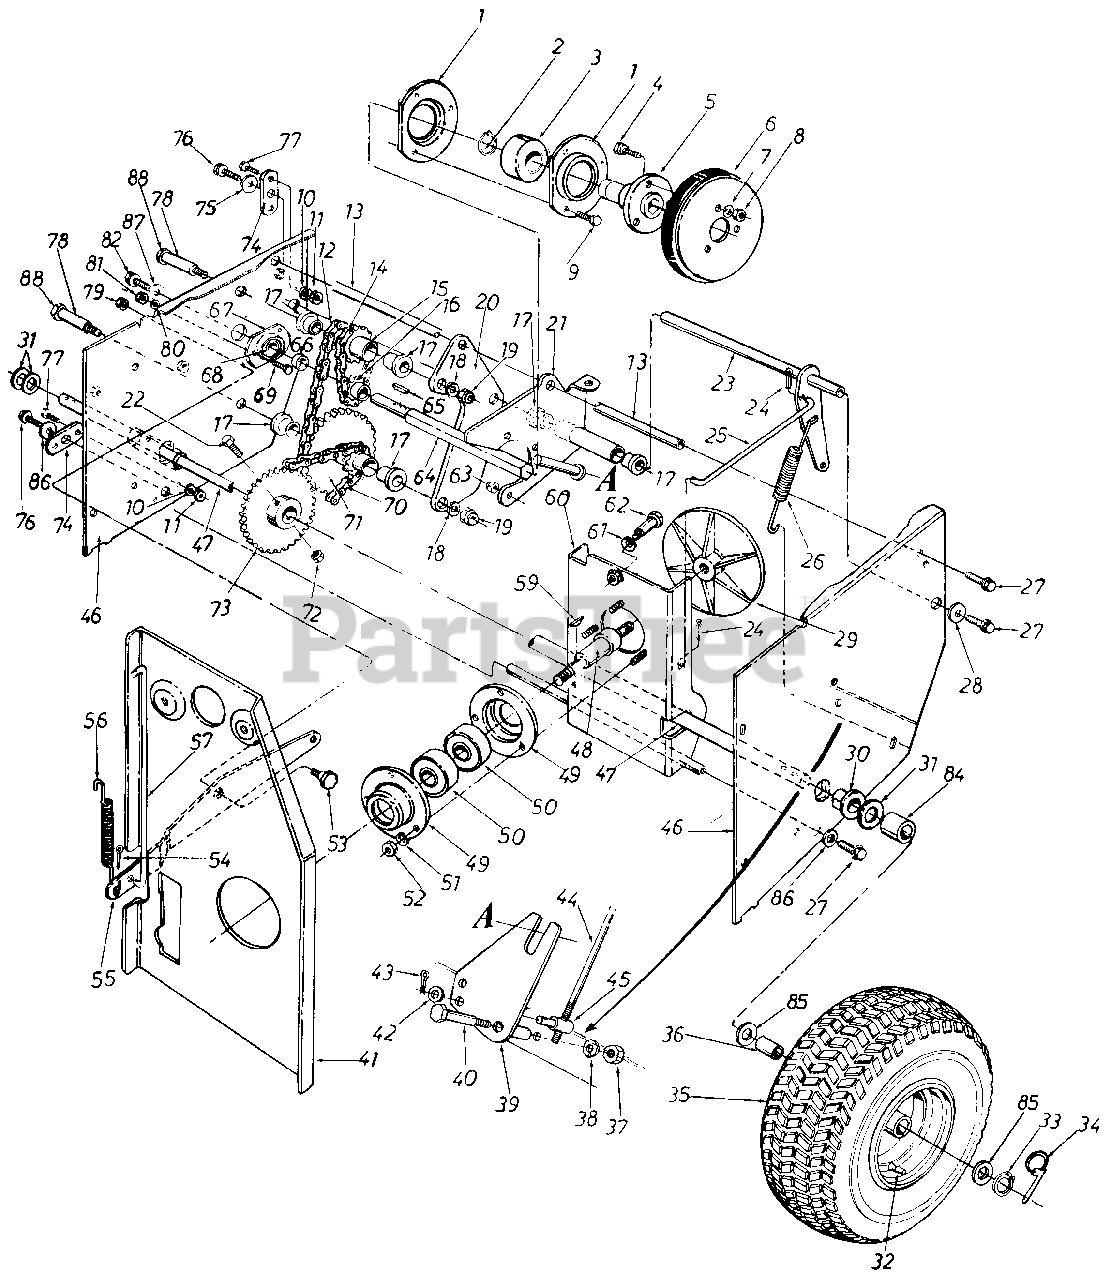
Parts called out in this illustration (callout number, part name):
1	Bearing Housing
2	Snap Ring-1.0" Dia.
3	Bail Brg. .25MM x 52MM x 15MM Thk.
4	Hex Sems Bolt 5/16-18 x .75" Lg.*
5	Friction Wheel Adapter
6	Friction Wheel Ass'y.
7	L-Wash. 5/16" I.D.*
8	Hex Nut 5/16-18 Thd.*
9	Hex Bolt 1/4-28 x .62" Lg.
10	L-Wash. 1/4" I.D.*
11	Hex Nut 1/4-20 Thd.*
12	#41 Chain-1/2" Pitch x 43 Links
12	Master Link (Service Only)
13	Sliding Support Axle
14	#41 Chain-1/2" Pitch x 19 Links
14	Master Link (Service Only)
15	9 and 14 Teeth Sprocket Hub Ass'y.
16	8 Teeth Sprocket
17	Flange Bearing .63" I.D.
18	L-Wash. 3/8" I.D.-H.D.
19	Hex L-Jam Nut 3/8-24 Thd.
22	Hex Bolt 1/4-28 x 1.5" Lg.
23	Drive Clutch Brkt. Ass'y.
24	Inter. Cot. Pin 5/16" Dia.*
25	Drive Clutch Rod .31" Dia. x 7.38" Lg.
26	Extension Spring 4.31" Lg.
27	Hex L-Bolt 5/16-18 x .62"
28	Fl-Wash. .345" I.D. x .75" O.D.
29	Aluminum Drive Plate
30	Flange Brg. w/Flats
31	Fl-Washer
32	Tubeless Air Valve
33	Snap Ring 3/4" Shaft
34	Klick Pin
35	Wheel Ass'y. Comp. 15 x 6
35	Rim Only
36	Bearing.75" I.D.
37	Hex Jam Nut 3/8-16 Thd.
38	L-Wash. 3/8" I.D.*
41	452 Engine Brkt. Ass'y.
42	Fl-Wash. .344" I.D. x .62" O.D.
43	Cotter Pin 3/32" Dia. x .75"-Lg.*
44	Shifting Rod
45	Adjustment Ferrule
46	452 Frame Ass'y.
47	Free Wheeling Axle
48	Drive Plate Spindle
49	Bearing Housing
50	Ball Brg. .787" I.D. x 1.85" O.D.
51	L-Wash. 5/16" I.D.
52	Hex Nut 5/16-18 Thd.*
53	Shld. Bolt .625" Dia. x .170" Lg.
54	Inter. Cotter Pin 5/16" Dia.*
55	Auger Clutch Brkt.
56	Extension Spring .38" O.D. x 3.18" Lg.
57	Auger Clutch Rod .31" Dia. x 10.62" Lg.
59	#61 Hi-Pro Key 3/16" x 5/8" Dia.
62	Shld. Bolt
63	Hex Ins. Jam Nut 1/4-28 Thd.
64	Hex Shaft
65	#9 Hi-Pro Key 3/32" x 5/8" Dia.
66	Spacer .51" I.D. x .69" O.D.
67	Bearing Housing
68	Ball Bearing
69	Hex Bolt 1/4-20 x .62" Lg.
70	#420 Chain .50" Pitch x 29 Links
70	Master Link
71	9 and 32 Teeth Sprocket Hub Ass'y.
72	Hex L-Nut 1/4-20 Thd.
73	22 Teeth Sprocket Hub Ass'y.
74	Pivot Axle Brkt.
75	Fl-Wash. .345" I.D. x .75"
76	Hex L-Bolt 5/16-18 x .62"
77	Hex Bolt 1/4-20 x .62" Lg.
78	Sprocket Hub Tubing 1.88"
79	Hex Cent. L-Nut 3/8-16 Thd.
80	L-Wash. 1/4" I.D.
81	Hex Nut 1/4-20 Thd.
82	Hex L-Bolt 5/16-18 x .62"
84	Spacer.75" I.D.
85	Fl-Washer
86	Fl-Wash. .344" I.D. x .875"
87	Bell-Wash. .345" I.D. x .88"
88	Hex Bolt 3/8-24 x 2.75" Lg.
